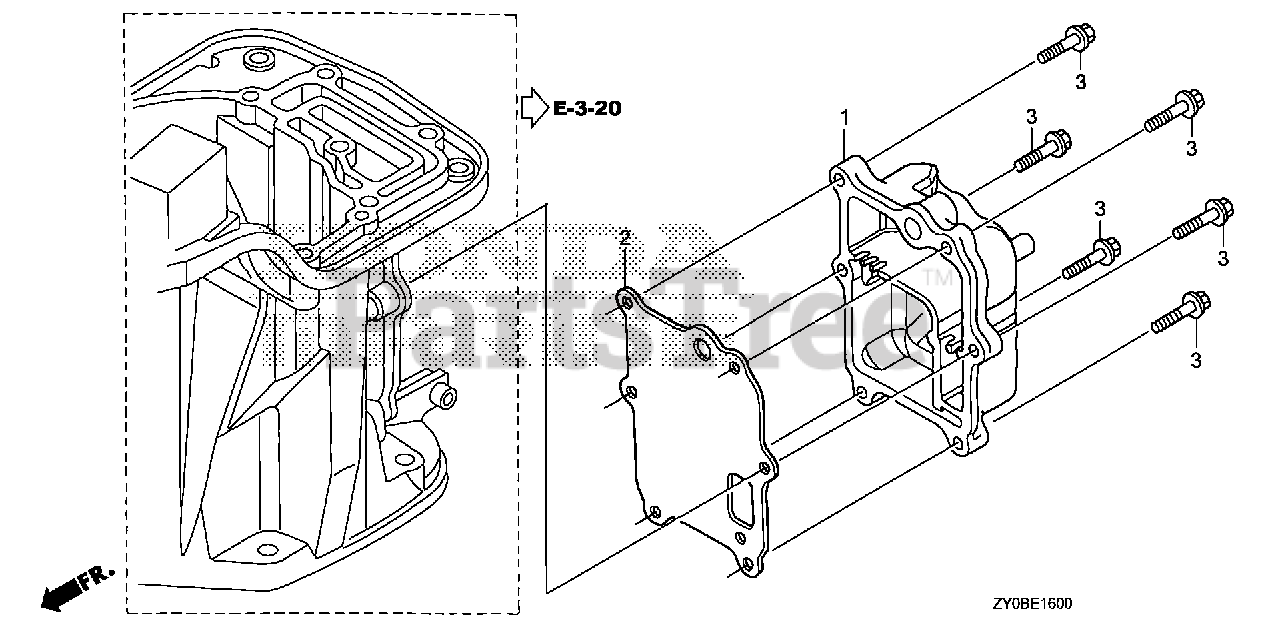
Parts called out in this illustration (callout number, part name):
1	COVER, EX. CHAMBER
2	GASKET, EX. CHAMBER
3	BOLT, FLANGE (6X23)
